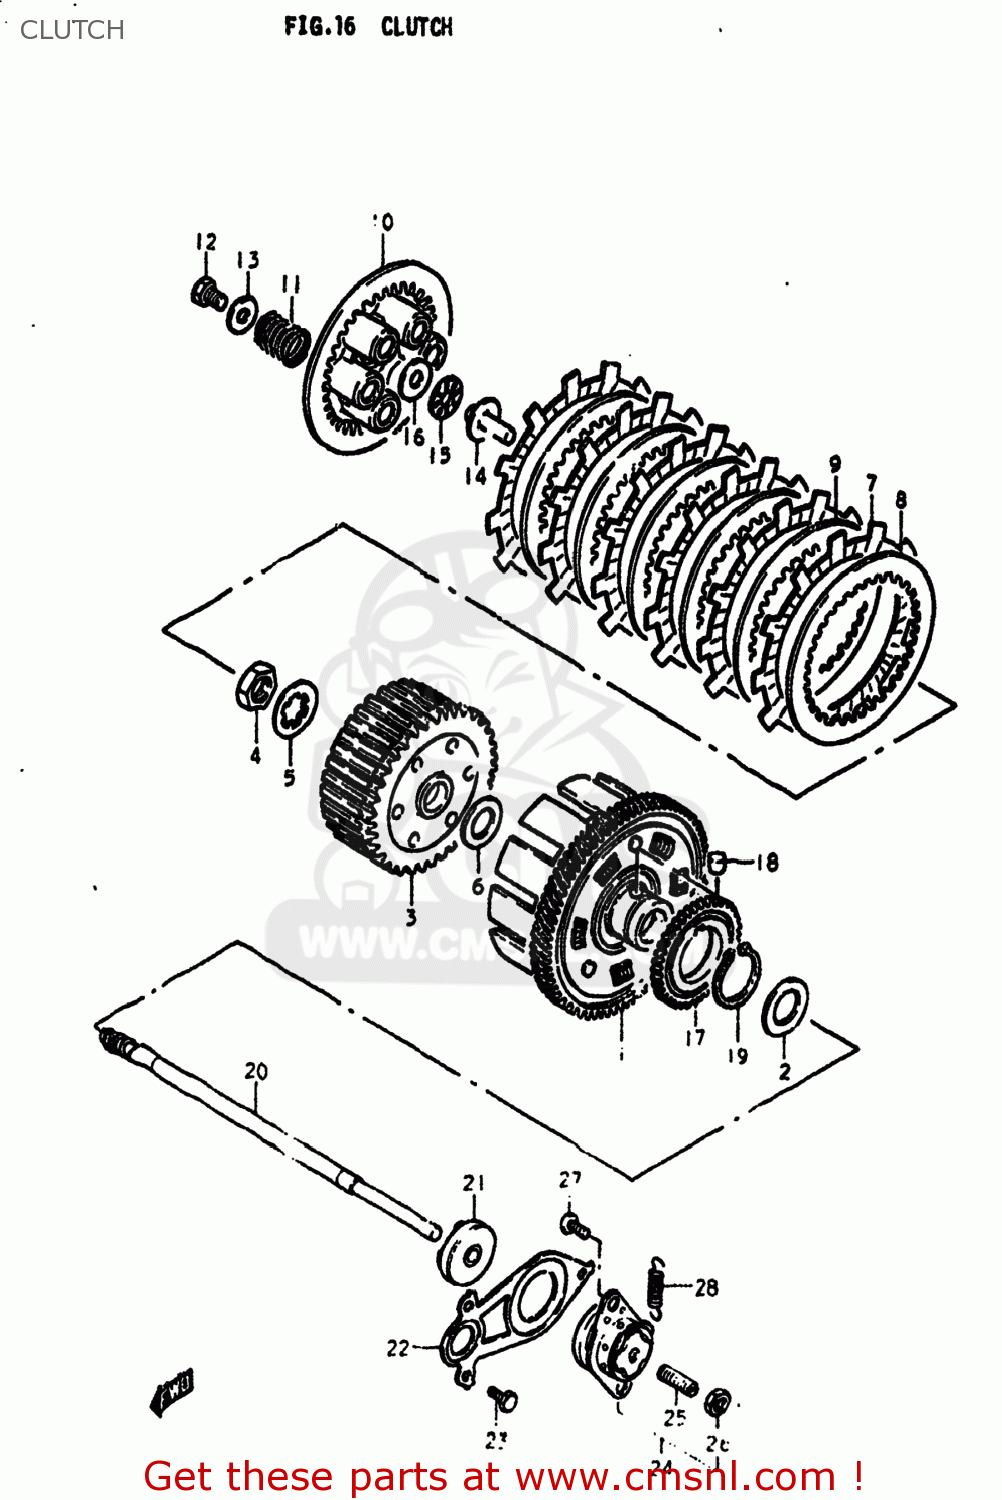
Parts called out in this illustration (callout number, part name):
1	GEAR ASSEMBLY,PRIMARY DRIVE
2	WASHER
3	HUB,CLUTCH SLEEVE
4	NUT (20MM)
5	WASHER,LOCK
6	WASHER(20X38X2)
7	PLATE,CLUTCH DRIVE (NAS)
8	PLATE,CLUTCH DRIVEN(T:2.0) (NAS)
9	PLATE,CLUTCH DRIVEN (NAS)
10	DISC,CLUTCH PRESSURE
11	SPRING
12	BOLT, UPPER
13	WASHER
14	PIECE,CLUTCH PUSH
15	BEARING(15X28X2)
16	WASHER
17	GEAR,OIL PUMP DRIVE
18	PIN(6X6)
19	CIRCLIP
20	ROD,CLUTCH PUSH
21	OIL SEAL
22	RETAINER,CL PUSH ROD OIL SEAL
23	BOLT
24	SCREW ASSEMBLY,CLUTCH RELEASE
25	SCREW
26	NUT 6MM
27	SCREW 6X12
28	SPRING
